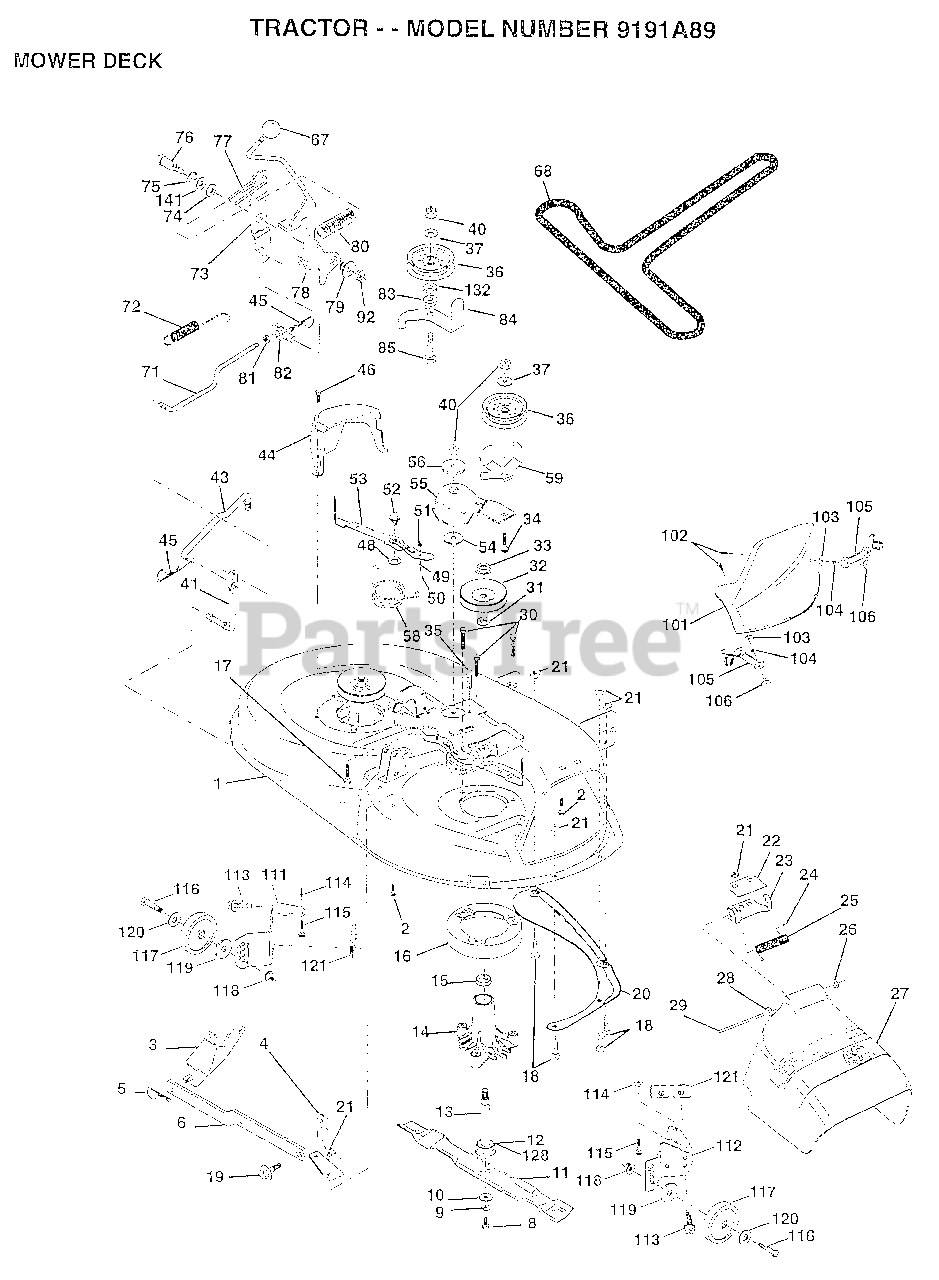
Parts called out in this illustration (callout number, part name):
1	DECK.WELD.42.
2	BOLT
3	BRKT ASM SWAY BAR
4	BRKT DECK SW BAR
8	BLADE BOLT
10	WASHER.HARD.BLADE
11	"BLADE.42"" MULCHER"
12	BEARING.BALL
14	HSG ASM MANDREL
15	BEARING
16	STRIPPER RND MWR
17	BOLT RDHD 3/8-16
18	BOLT
19	BOLT SHD 5/16-18
20	BAFFLE VORTEX 42
22	STIFFENER BRKT
23	DEFLECTOR BRKT
25	SPRING TORSION
27	DEFLECTOR.SHIELD
28	WASHER
29	HINGE ROD
30	"SCREW-THD ROLL,WA"
31	WASHER
32	PULLEY.MANDREL.42
34	BOLT
35	XMAS TREE FASTNER
36	FLAT IDLER PULLEY
37	WASHER
41	PIVOT ROD
43	ROD CLUTCH W/NIBS
44	GUARD MAND LH BLK
46	SCREW.1/4-20X5/8
48	HARD SMALL WASHER
49	ROLLER ASM-CAM
50	SHOULDER BOLT
51	LOCKNUT
52	BOLT.SHLD.5/16-18
54	HARDENED WASHER
55	ARM-IDLER
56	SPACER RETAINER
58	SPRING TORSN BRAK
59	GUARD IDLER TUV
67	KNOB.RD.7/16-14
68	BELT.V.T-PATH
71	ROD CLUTCH 38/42
72	RETURN SPRING
73	CLUTCH ARM SECOND
74	WASHER
75	RING
76	SHOULDER BOLT
77	SPRING KEEPER
78	LEVER.ASM.CLUTCH
79	BUSHING
80	SPRING.CLUTCH.MWR
81	NUT
82	TRUNION ADJ
83	WASHER
84	"KEEPER-BELT,FIXED"
85	BOLT RDHD 3/8-16
92	NUT
101	"COVER.MULCH.42"""
102	SCREW
103	WASHER #10
104	LOCKWASHER
105	LATCH ASSY.BAGGER
106	WELDNUT
111	BRACKET.GWHL.LH.
112	BRACKET.GWHL.RH.
113	SCREW
116	BOLT M
117	WHEEL.GAGE.BLK.PL
118	LOCKNUT
119	WASHER
120	WASHER
121	BRACKET.EXTRD.GWL
128	WASHER.FELT.
132	WASHER GT
141	WASHER .T
